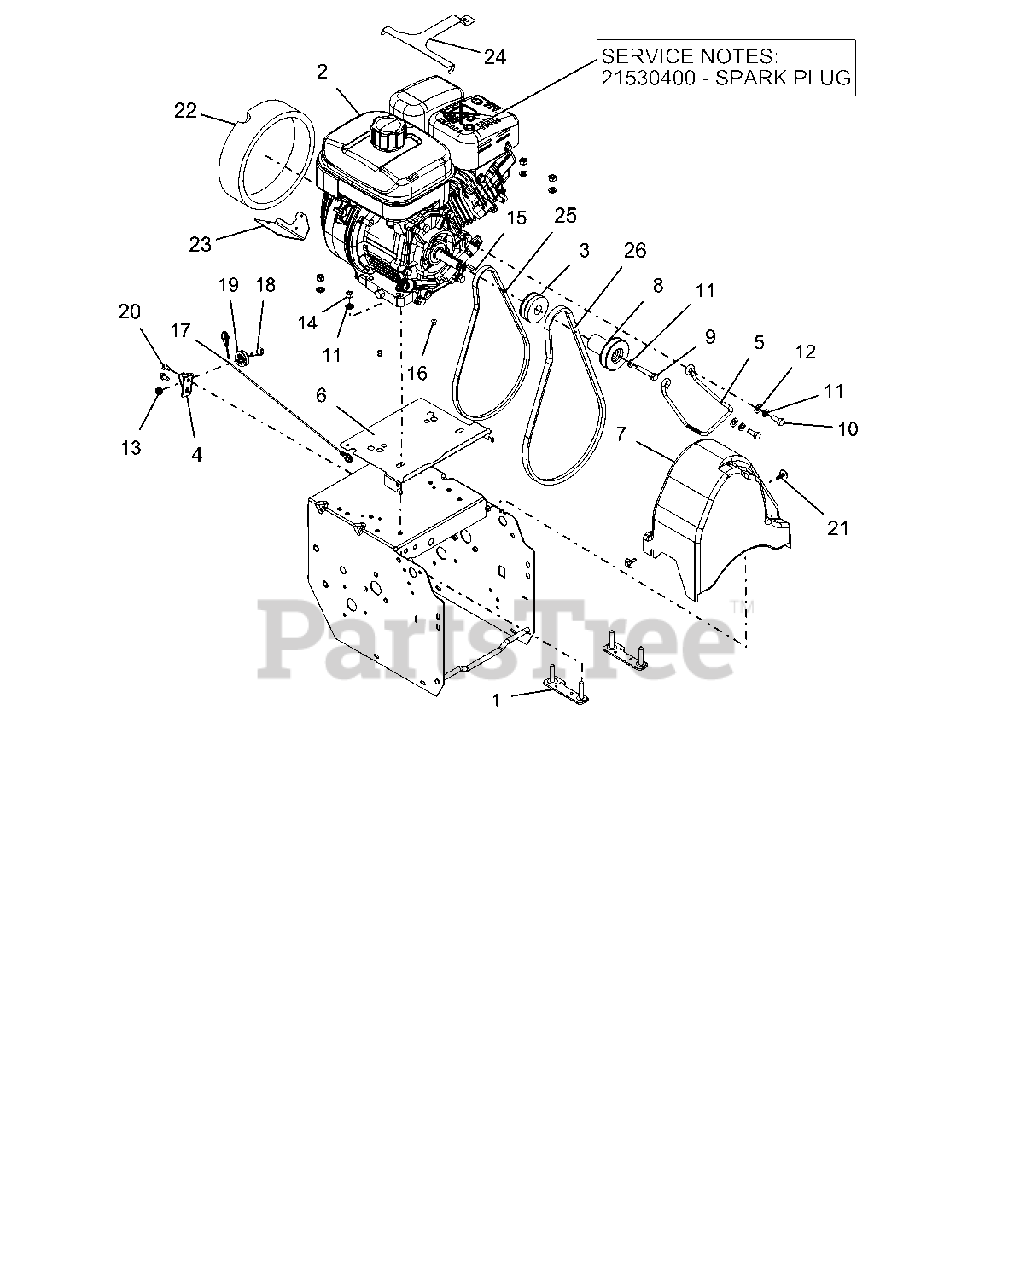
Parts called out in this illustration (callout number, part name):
1	WLDMT, STRAP ENGINE BOLT
2	ENGINE, SUBARU - EX17 120V ALL SEASON
2	SPARK PLUG
3	PULLEY, TRACTION
4	BRKT, CABLE PULLEY
5	FINGER, BELT
6	BAFFLE, COMPACT
7	COVER, BELT
8	SHEAVE, AUGER DRIVE
9	BLT-HEX .31-24X1.75 GR5 YWZC
10	BLT-HEX .31-24X.75 GR5 YWZC
11	WSHR-LK .31X.097 HVY YWZC
12	WSHR-FL-STL.344X.688X.065YWZC
13	NUT, LK-CTR-FLG .25-20 YWZC
14	NUT-HEX .31-18 YWZC
15	KEY-SQ .188X.188X.750
16	RVT-POP .187x.250 (#64) YWZC
17	CABLE, LOWER TRACTION
18	BOLT, SHLDR -.375 X .375 X .25-20
19	PULLEY, CABLE
20	SCR-TAP .25-20X.50 HWH TR YWZ
21	SCR, TAP .25-20 X.5 CAPTIVE
22	COVER, FOAM - SUBARU RECOIL
23	BRKT, SWITCH -SUBARU
24	GUARD, SNO - ASUBARU EX17
25	V-BELT, 3L-WRAPPED CLUTCHING
26	V-BELT, HA-Raw Edge Laminated
